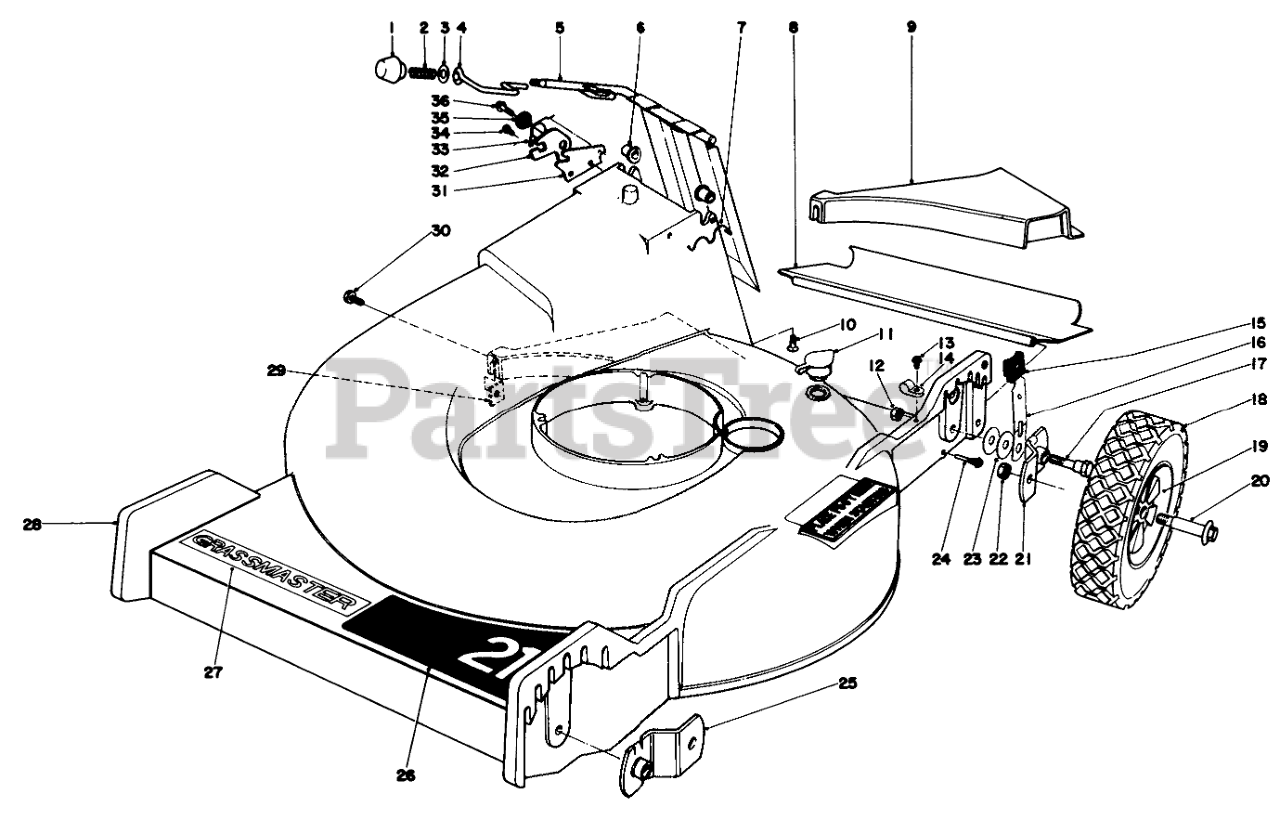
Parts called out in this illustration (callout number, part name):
2	COMPRESSION SPRING
3	WASHER
4	DOOR LATCH
5	Door Handle
6	BUSHING-NYLON
7	Door Retainer
8	REAR SAFETY SHIELD
9	REAR INSERT
10	SCREW-HH
11	WASHOUT PLUG
12	Nut
13	SCREW
14	CABLE CLAMP
15	KNOB-ARM
16	SPRING ARM ASM
17	PIVOT SCREW
19	Wheel & Tire Assembly (Incl. Ref. #18)
20	BOLT-WHEEL
21	PIVOT ARM ASM A
22	Nut
23	WASHER-PIVOT
24	SAFTEY SHIELD SCREW
25	PIVOT ARM ASM B
26	Decal
27	Decal Grassmaster
28	Housing
29	SPECIAL NUT
30	SCREW THD 1/4 20 5/8
31	DOOR LATCH PLATE
32	Latch Safety
33	TORSION SPRING
34	SCREW-HWH
35	Latch Spacer
36	Screw
